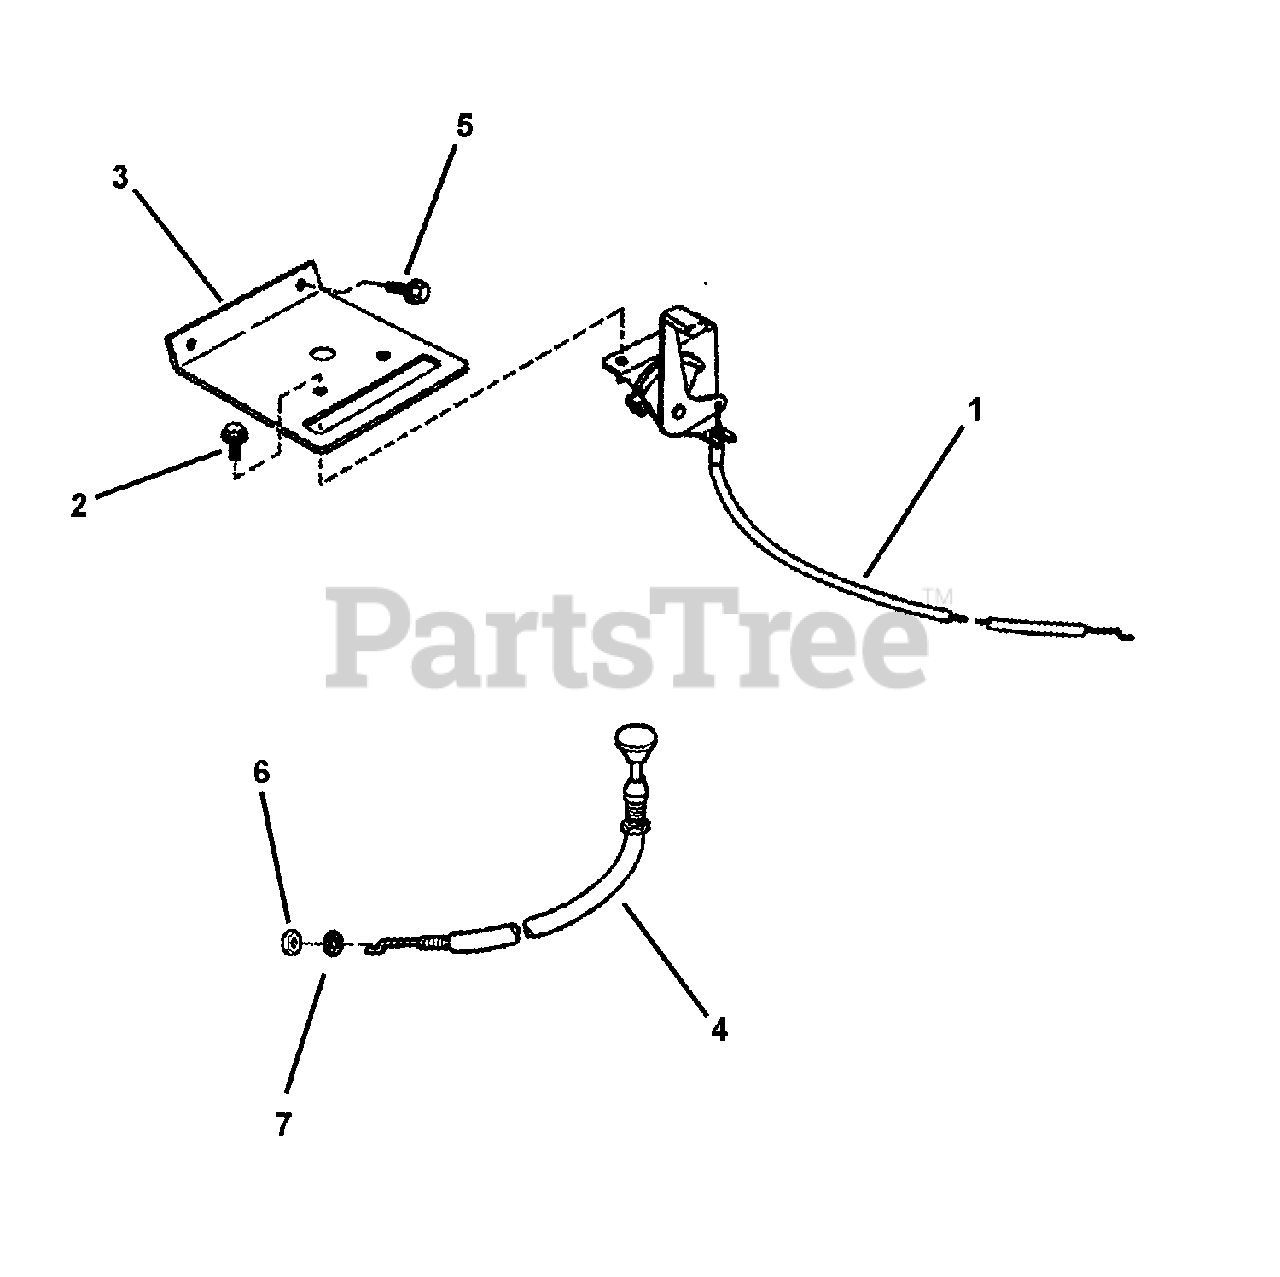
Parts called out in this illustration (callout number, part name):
1	CONTROL, Throttle (33.6" long) (Briggs 18 & 20 HP Engine)
2	SCREW, #10-24 x 1/2" Hex Washer Self-Tap (Torx)
3	PLATE, Throttle Control
4	CONTROL, Choke (44" long)
5	SCREW, 1/4-20 x 1/2" Hex Washer Self-Tap
6	NUT, 3/8-24 Hex, GR B
7	WASHER, 3/8" Internal Tooth Lock
